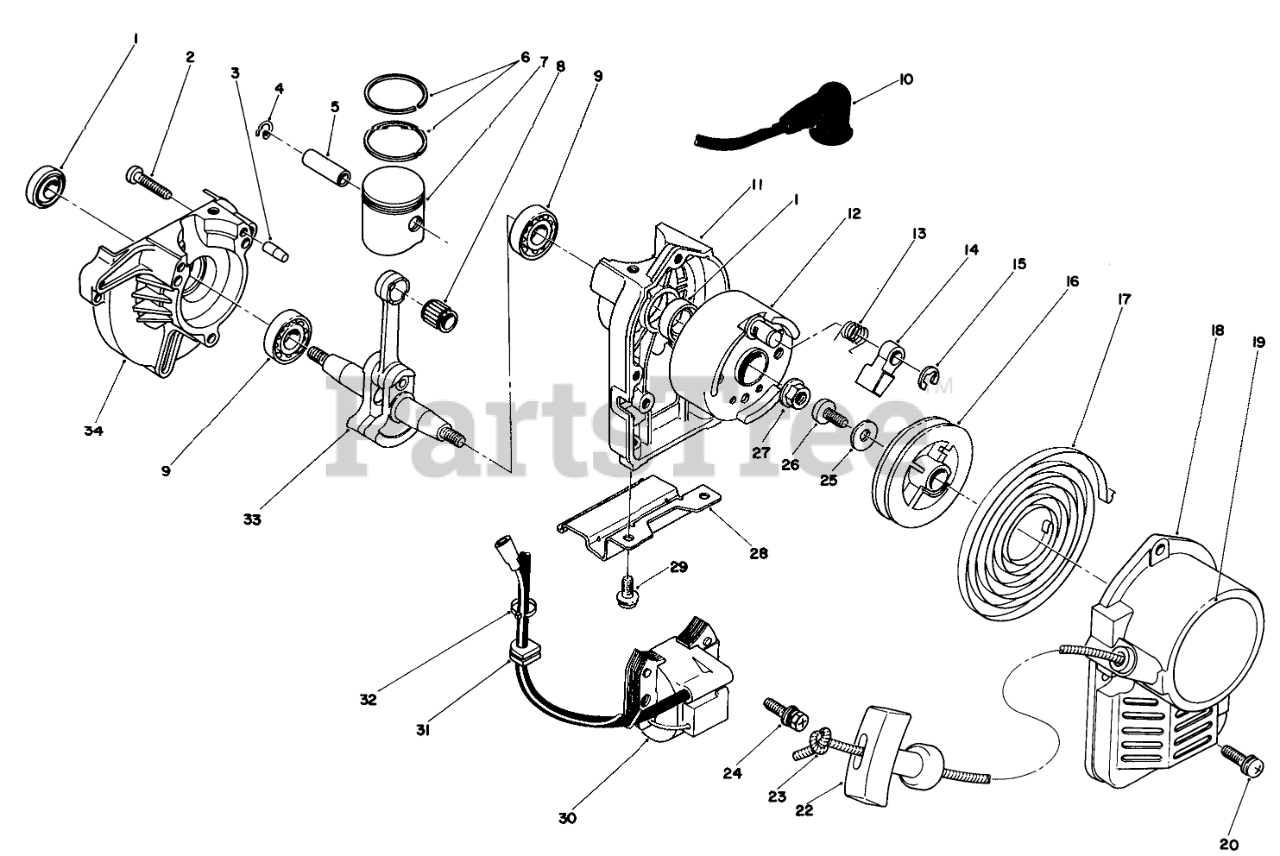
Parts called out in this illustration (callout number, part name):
1	OIL SEAL
2	Screw
4	PISTON PIN CLIP
5	PISTON PIN
6	PISTON RING
7	Piston Assembly (Incl. Ref. #5)
8	NEEDLE BEARING
9	BEARING
10	CAP-PLUG
11	STARTER CASE
12	Rotor
13	Spring-Return
14	RATCHET
15	SNAP RING
17	SPRING
18	Case, Starter
19	RECOIL COVER DECAL
20	SCREW & WASHER
22	Knob-Starter
23	Rope-Recoil
24	BOLT & WASHER
25	WASHER
26	SCREW
28	STAND
29	SCREW & WASHER
30	IGNITION COIL
31	GROMMET
33	CRANKSHAFT ASM
34	DRIVE CASE
